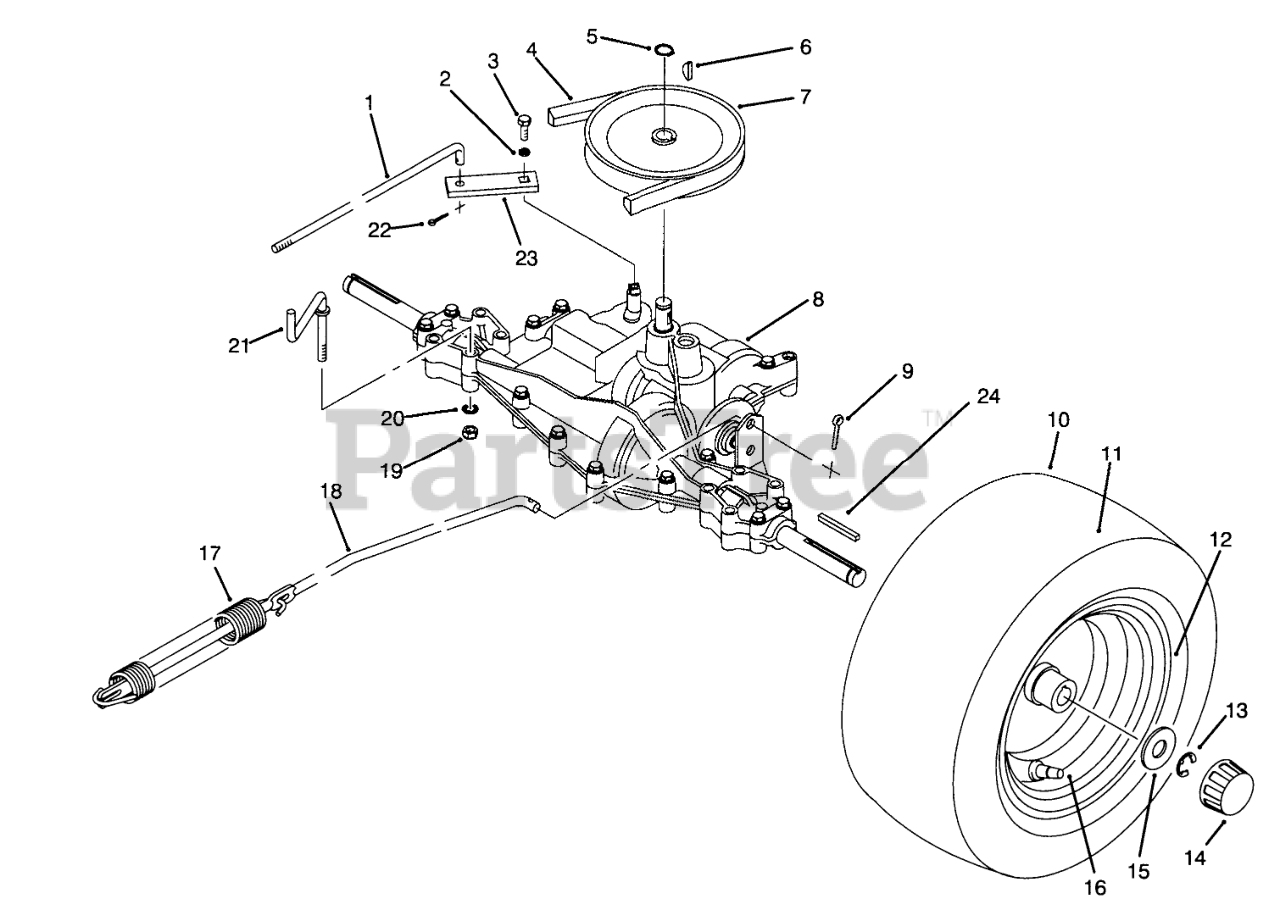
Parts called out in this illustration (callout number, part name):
1	LINK-SHIFT
2	WASHER-LOCK
3	SCREW-HH
4	V-BELT, TRACTION
5	RING-SNAP, EXTERNAL
6	KEY-WOODRUFF
7	PULLEY-TRANSAXLE
8	TRANSAXLE 915-019
9	PIN-COTTER
11	TUBE-INNER
12	REAR WHEEL ASM
13	E-RING
14	CAP-HUB
15	WASHER-PLAIN
16	STEM-VALVE
17	SPRING-EXT
18	ROD-BRAKE
19	NUT-LOCK, NI
20	WASHER-LOCK, INTERNAL
21	GUIDE-LOWER BELT
22	PIN-COTTER
23	LINKAGE
24	KEY-SQUARE
